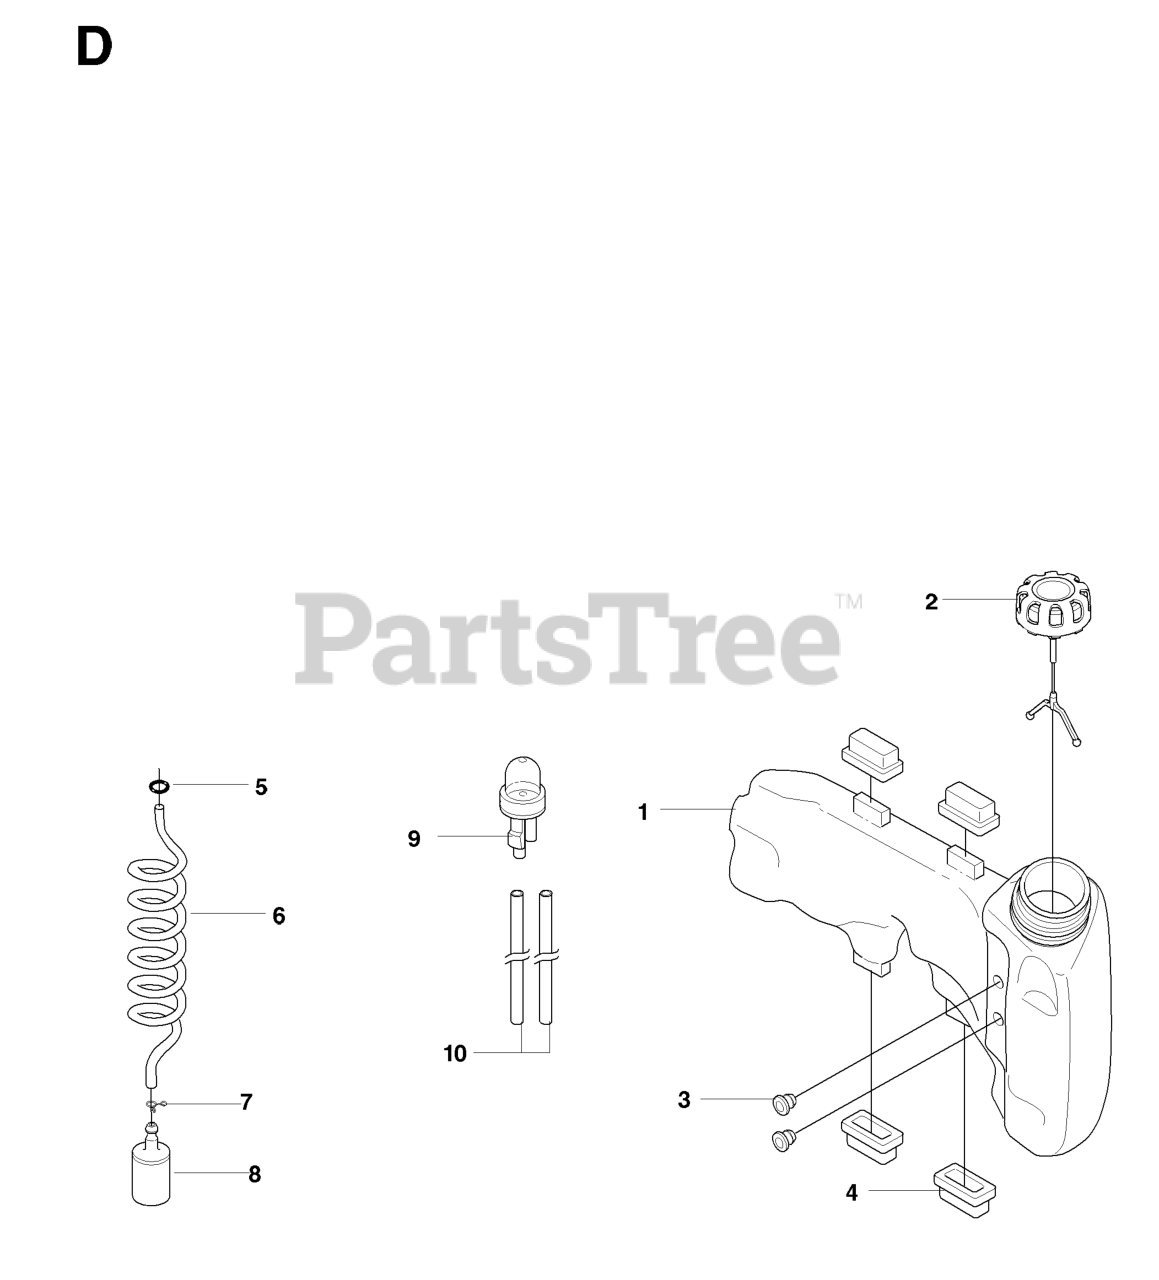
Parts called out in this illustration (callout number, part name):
3	FUEL TANK BUSHING
8	RP FUEL FILTER
9	AIR PURGE BUBBLE
10	HOSE
